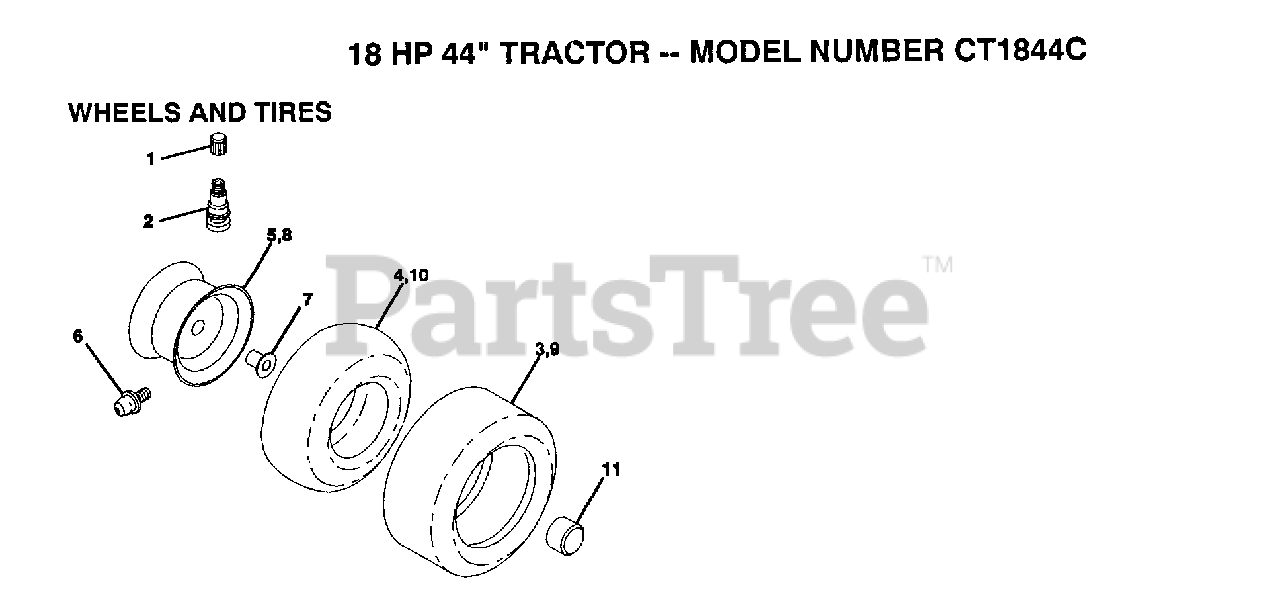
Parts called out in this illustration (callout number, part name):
1	VALVE CAP
2	VALVE STEM LT
3	FITTING LT
5	TUBE.5.3/4.5/6
7	HUB CAP
8	"FLANGE, BEARING"
10	TUBE.18X9.5-8
